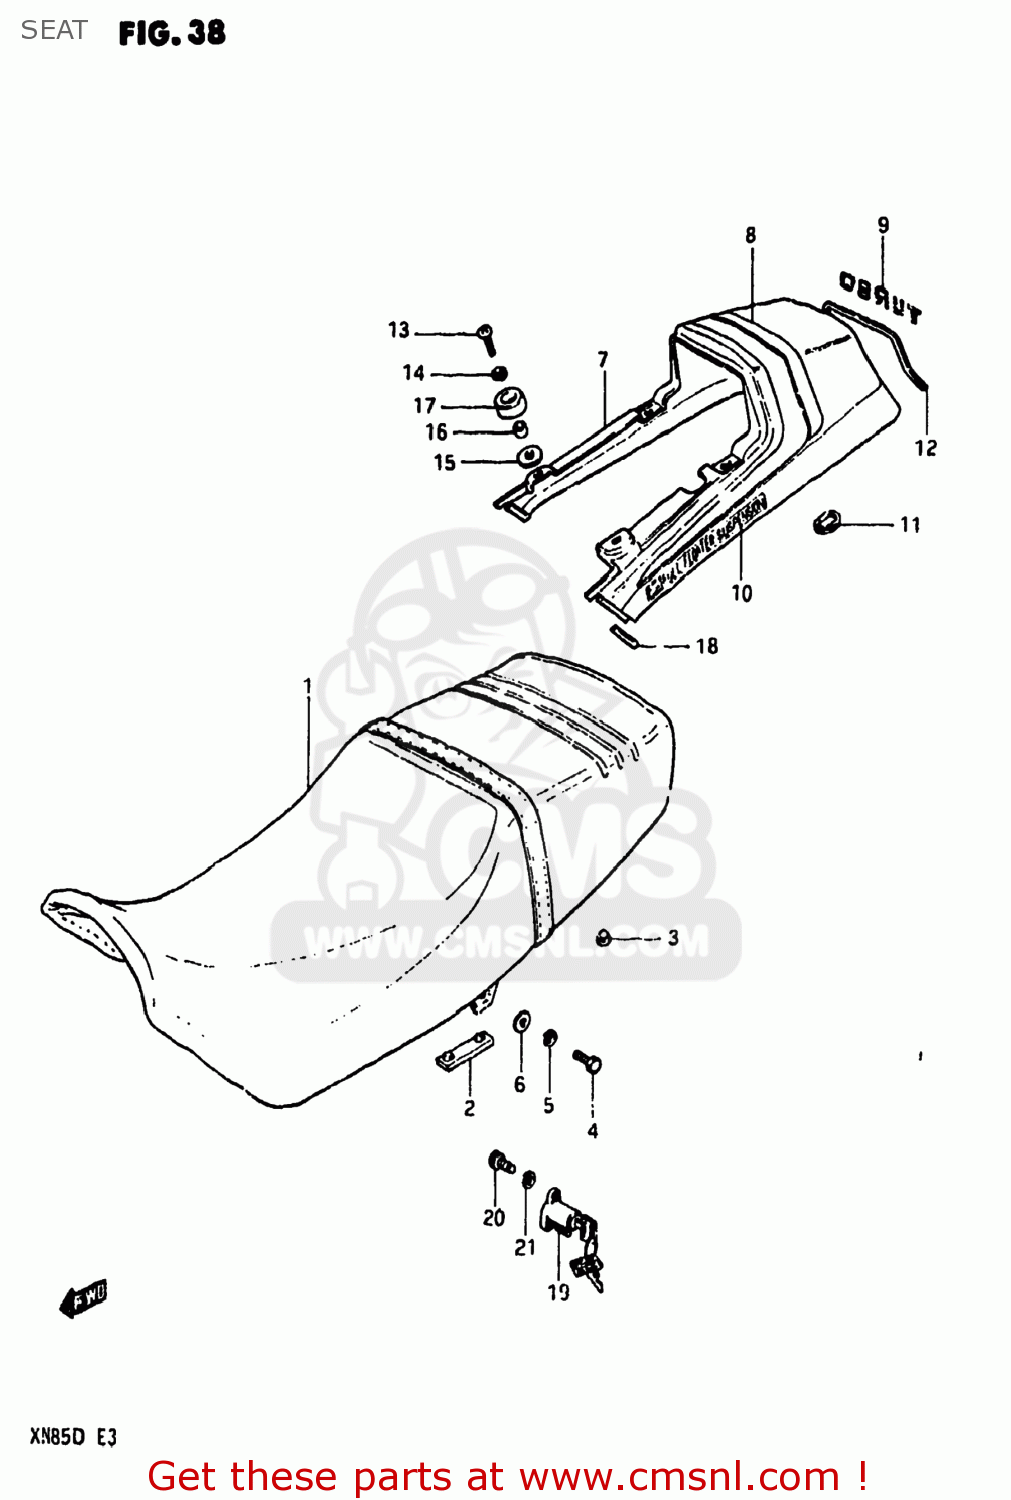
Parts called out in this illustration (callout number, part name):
1	SEAT ASSEMBLY
2	CUSHION
3	CUSHION
4	BOLT
5	LOCK WASHER
6	WASHER
7	BOX ASSEMBLY,SEAT TAIL
8	TAPE SET,BOX SEAT TAIL
9	EMBLEM (TURBO)
10	EMBLEM,FULL FLOATER
11	CUSHION
12	MOLDING,SEAT TAIL COVER
13	SCREW
14	LOCK WASHER
15	WASHER (6.5X24X1.6)
16	SPACER
17	CUSHION,COVER
18	CUSHION, FRONT
19	LOCK SET
20	BOLT 6X11
21	LOCK WASHER
